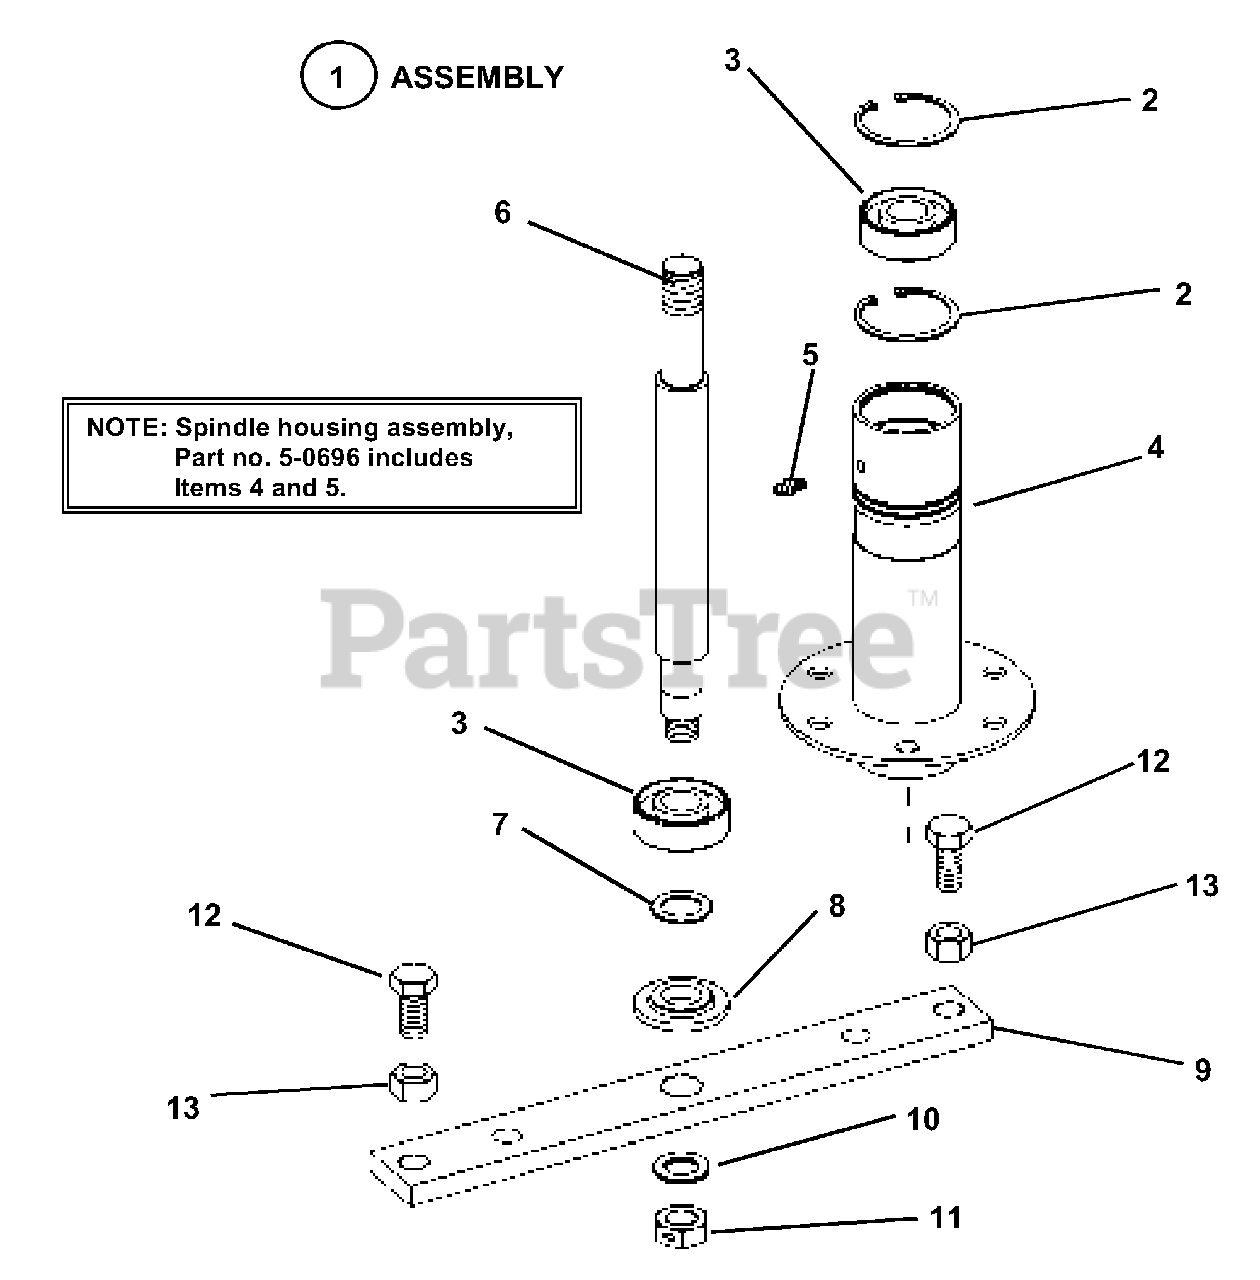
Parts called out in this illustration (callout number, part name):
1	ASSEMBLY, Spindle Housing
2	RING, 1.85" Internal Retaining
3	BEARING, Spindle
4	WELDMENT, Spindle Housing
5	FITTING, Lube (Press fit for .187 hole-no ball)
6	SPINDLE, Shaft (10.237" Long)
7	WASHER, 3/4 Shim
8	WASHER, Spindle
9	HOLDER, Blade
10	SPACER, Blade Centering
11	NUT, 5/8-18 Hex Center Lock
12	SCREW, 1/2-20 x 1-1/4" Hex Head Cap, Grade 5
13	NUT, 1/2-20 Hex Jam
